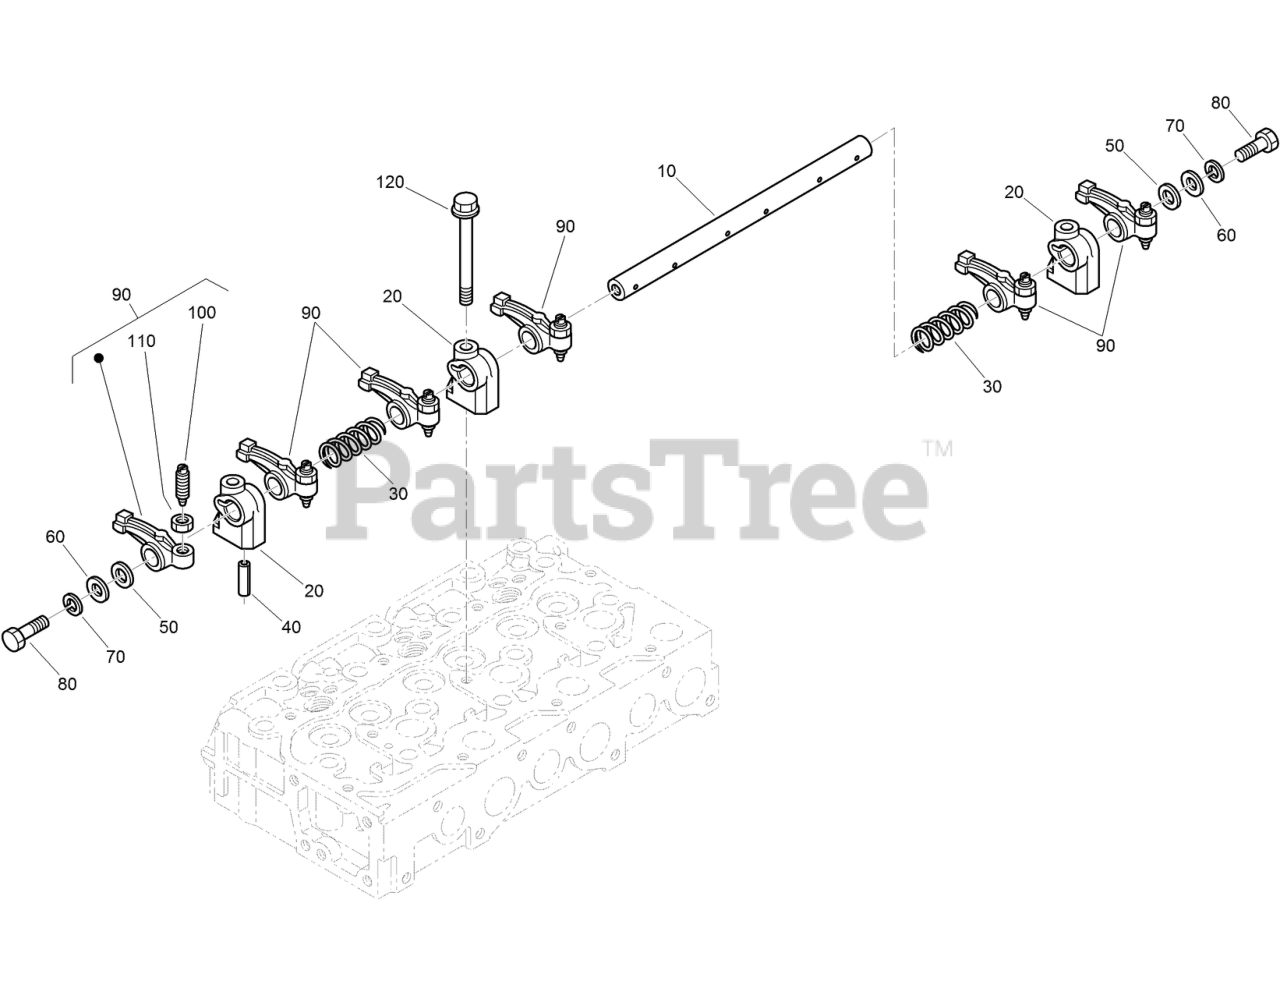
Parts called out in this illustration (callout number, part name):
10	SHAFT-ARM, ROCKER
20	BRACKET-ARM, ROCKER
30	SPRING-ARM, ROCKER
40	PIN-SPRING
50	WASHER
60	WASHER-PLAIN
70	WASHER-SPRING, LOCK
90	ROCKER ARM ASM
100	SCREW-ADJUSTING
120	BOLT-FLANGE
